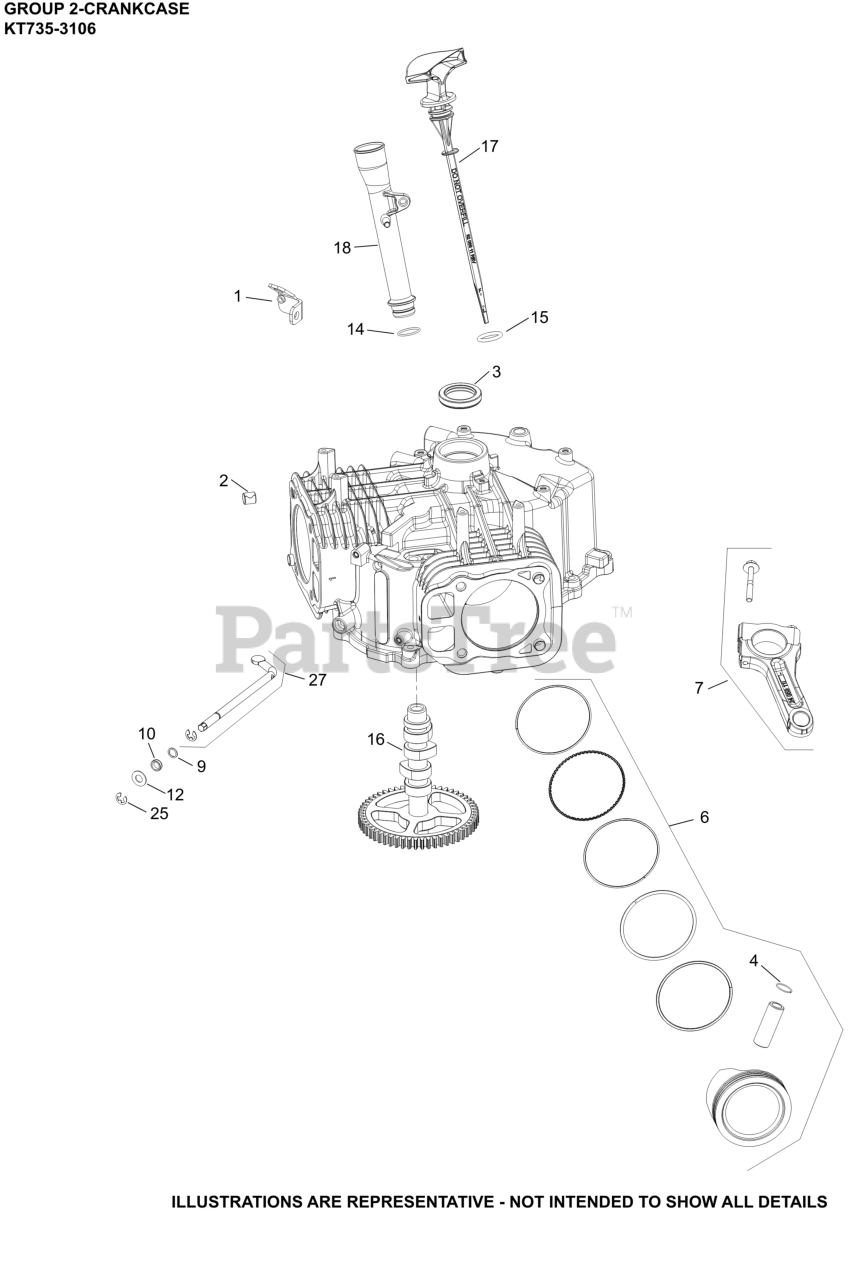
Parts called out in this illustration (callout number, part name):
1	BRACKET, OIL FILL TUBE
2	PIN, LOCATING
3	SEAL, OIL (HELIX LIP)
4	RETAINER, PISTON PIN
6	KIT, PISTON 725CC (STD) STYLE B
7	ROD, ASSEMBLY CONNECTING
9	WASHER, FLAT 11/32"
10	SEAL, GOVERNOR CROSS SHAFT
12	WASHER, FLAT 9 MM
16	CAMSHAFT ASSY
17	DIPSTICK, ASSY
18	TUBE ASSEMBLY, OIL FILL
25	CLIP, RETAINER GOVERNOR SHAFT
27	KIT, CROSS SHAFT
